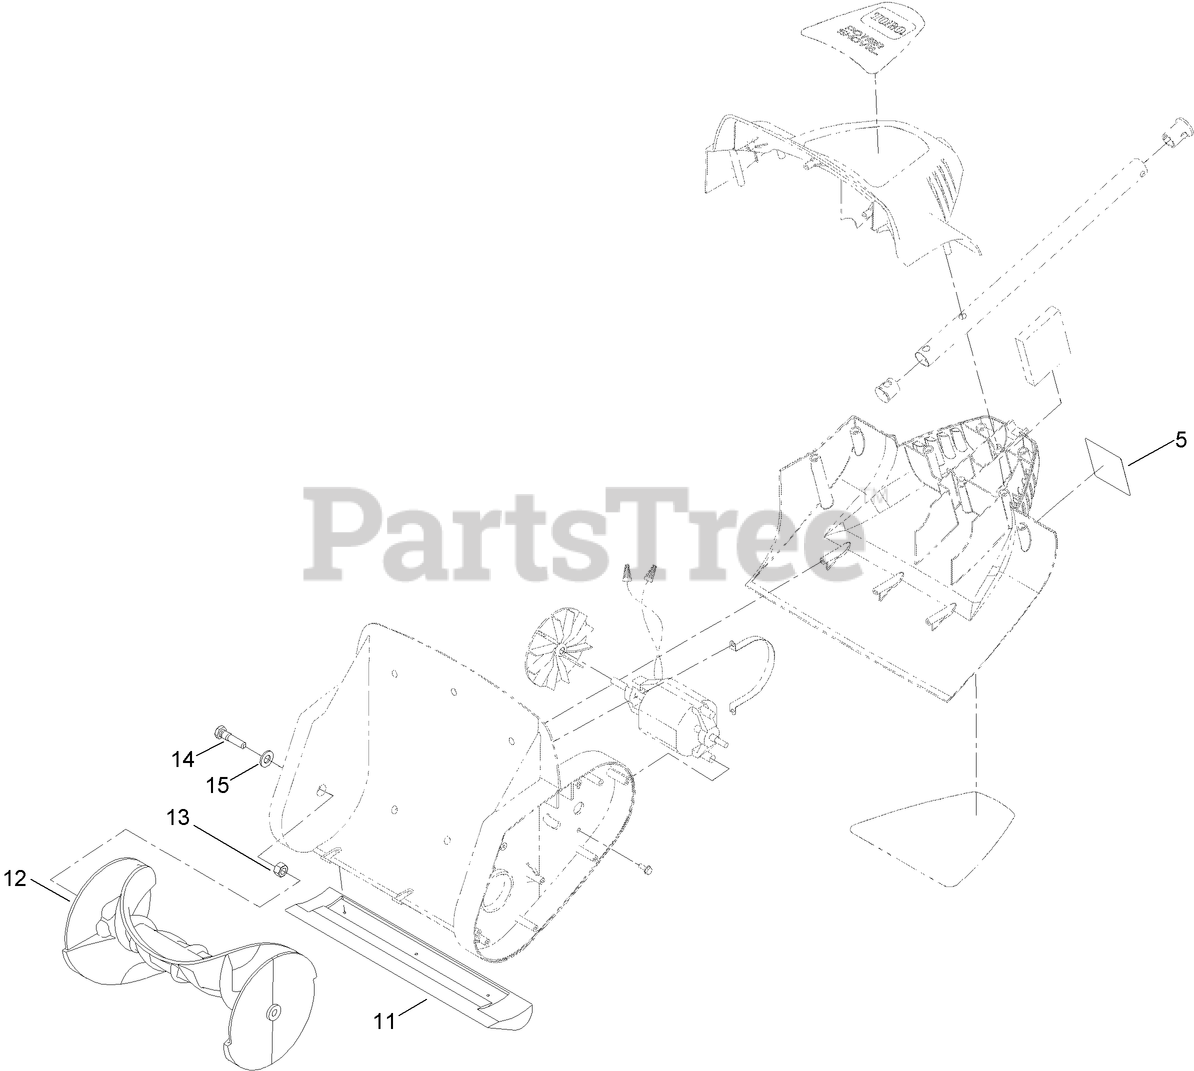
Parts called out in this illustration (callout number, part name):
5	DECAL-DANGER
11	SCRAPER-SNOW
13	NUT-LOCK
14	PIN-ROTOR
15	WASHER-PLAIN
